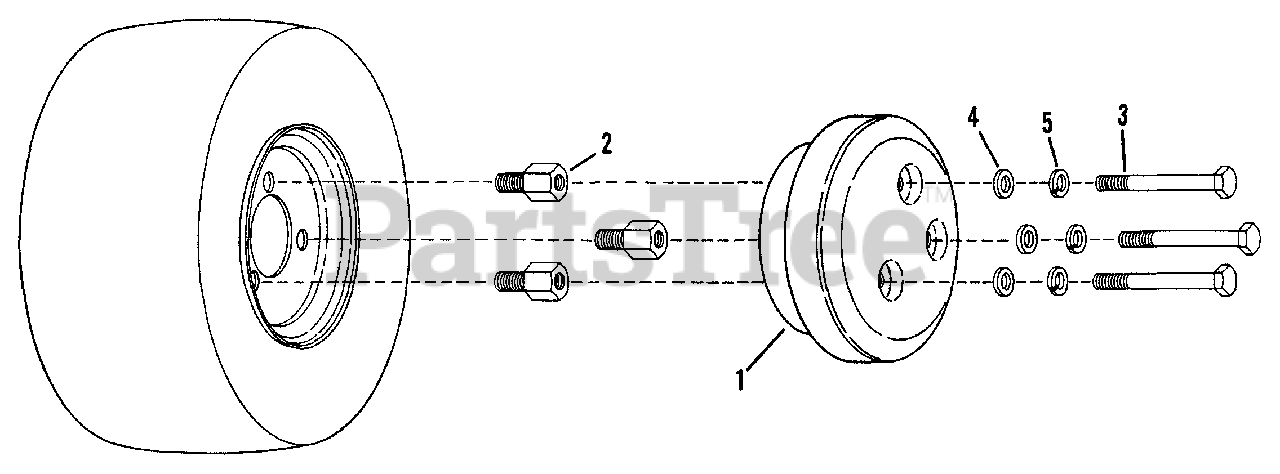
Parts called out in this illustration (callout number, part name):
1	WEIGHT, Wheel
2	STUD, Wheel
3	SCREW, 3/8-16x4 1/2" Hex Head Cap
4	WASHER, 3/8" Flat
5	WASHER, 3/8 Split Lock
